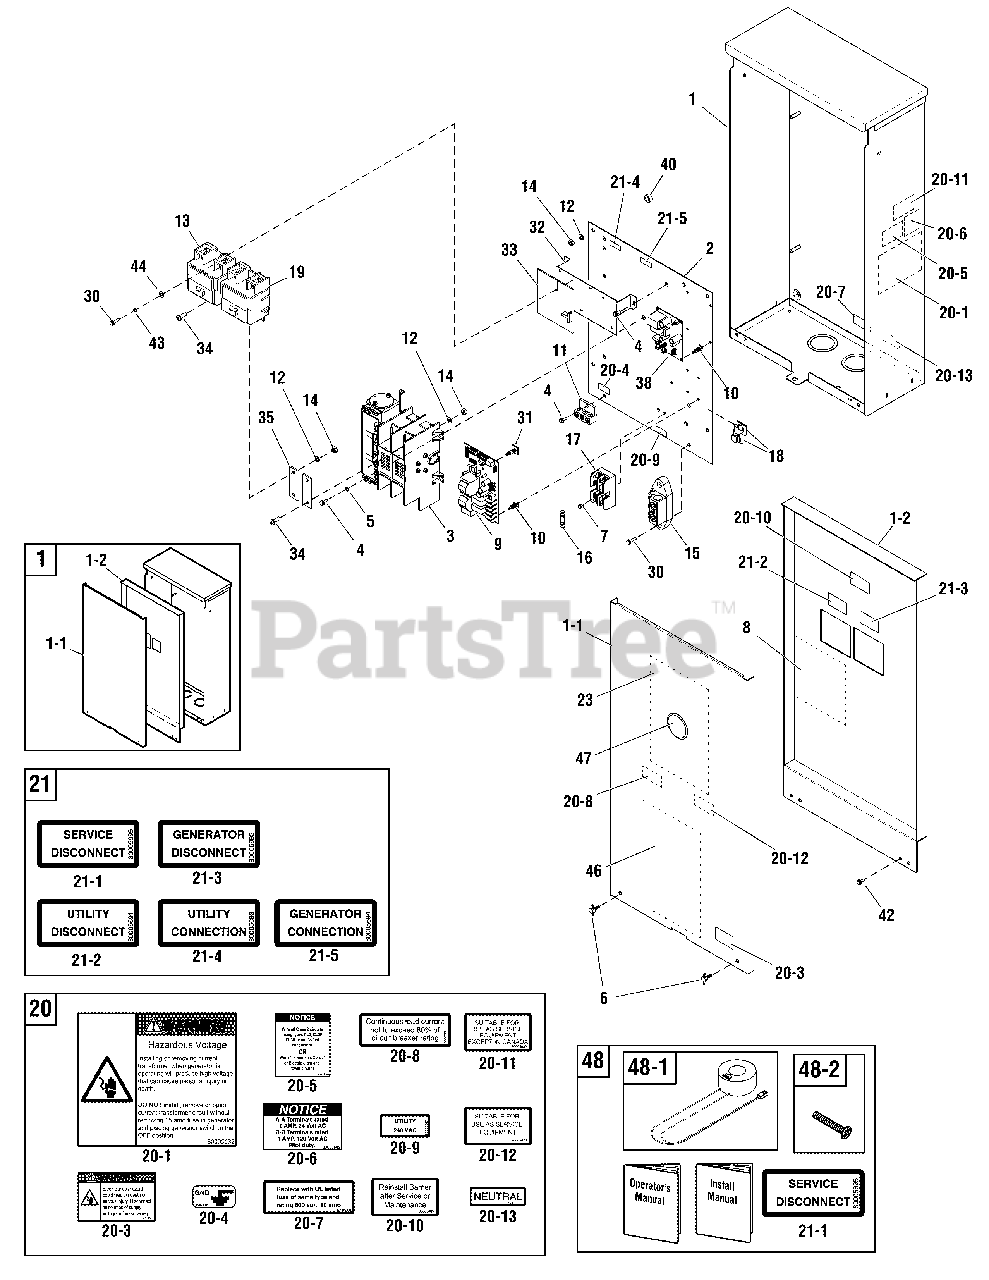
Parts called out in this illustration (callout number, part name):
1	ENCLOSURE
2	BACK PANEL
3	SWITCH, Transfer
4	* TRILOBULAR, #10-32 x 1/2
5	* WASHER, External Tooth, #10
7	* SCREW, Hex Head, Trilobular, #6-32 x 3/8
9	BOARD, Circuit
11	LUG
12	* WASHER, Lock, 1/4
13	BREAKER, Circuit, 200A
14	* NUT, 1/4-20
19	BREAKER, Circuit, 200A
20	DECAL SHEET- WARNINGS
20-1	DECAL, Warning Voltage
20-3	DECAL, Warning Shock
20-4	DECAL, Ground
20-5	DECAL, Notice
20-6	DECAL, Contacts Rated
20-7	DECAL, Fuse
20-8	DECAL, Circuit Breaker
20-9	DECAL, Sensing, Utility
20-10	DECAL, Reinstall AFter
20-11	DECAL, Not Sutiable
20-12	DECAL, Suit. as Service Equip.
20-13	DECAL, Neutral
21	DECAL SHEET - CONNECTIONS
21-1	DECAL, Service Disconnect
21-2	DECAL, Utility Disconnect
21-3	DECAL, Gen Disconnect
21-4	DECAL, Utility Connection
21-5	DECAL, Gen Connection
30	* SCREW, Hex Head, Trilobular, #10-32 x 3/4
34	* SCREW, Phillips Head, 1/4-20x 3/4
40	SPACER
42	* TRILOBULAR, #10-32 x 3/8
43	* WASHER, Lock, #10
44	* WASHER, Flat, #10
48	KIT, Manual
